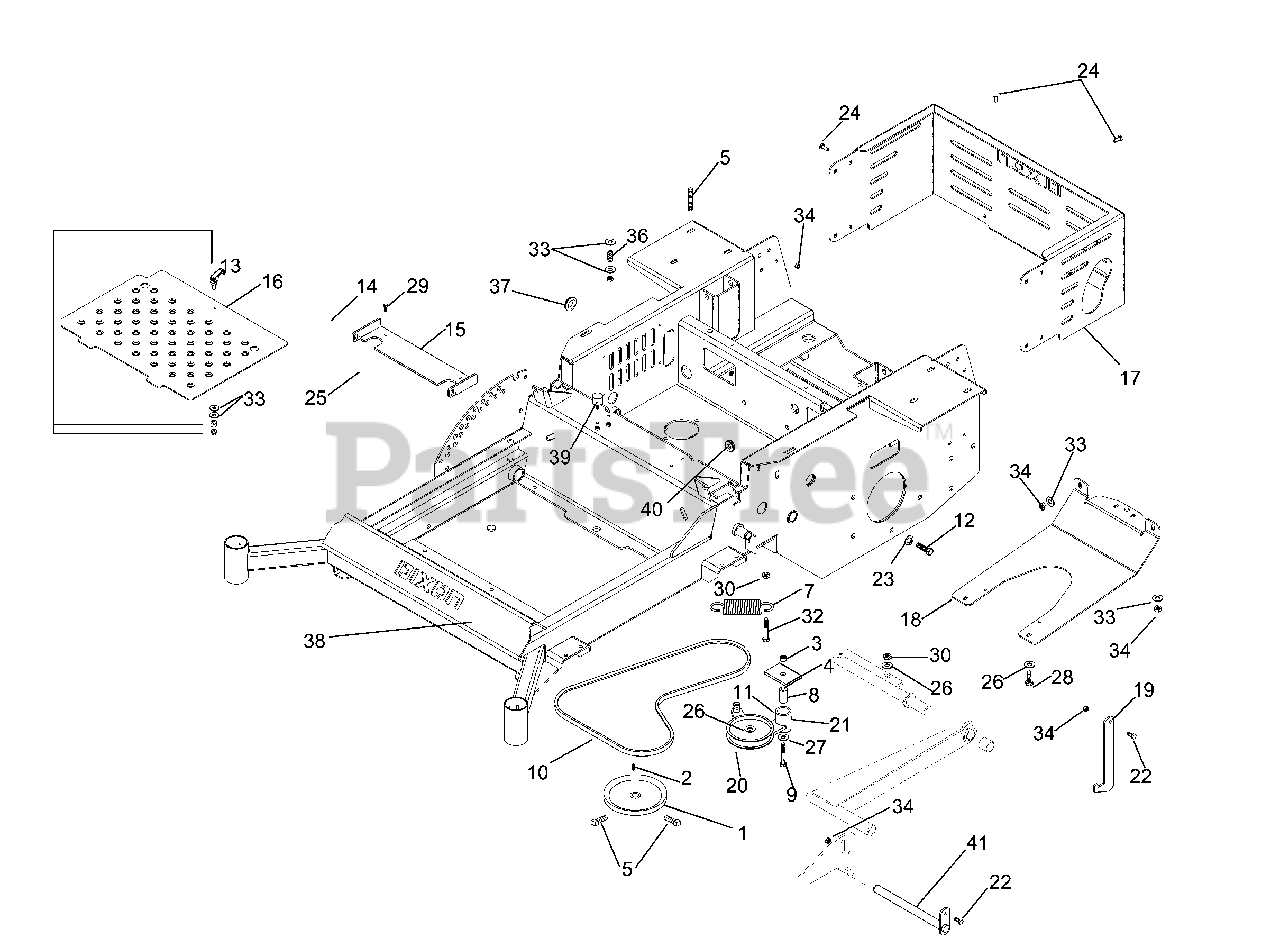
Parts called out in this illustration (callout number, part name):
2	KEY 5 MM SQ X 25 MM
3	NUT 1/2-13 HEX NYLOC ZD
5	STUD, 5/16C
6	SCREW 5/16C X 5/8 SQ HEAD
8	PIVOT BUSHING
9	HCS 1/2C X 3 1/4
10	PUMP BELT
11	IDLER ARM WLDT
12	HEX SCREW 7/16-14 X 1 GR8
13	LATCH.SWELL.ACTION
14	CLEVIS PIN 3/8
15	PLATE, MOUNT, SEAT
16	FLOOR PLT W/DECAL
17	GRD, REAR W/DECAL
18	PLATE, SKID
19	STOP, SEAT
20	IDLER PULLEY
21	ZERK
22	HCS 5/16C X 1
23	WASHER 7/16 LOCK
24	BOLT 5/16C X 3/4" CARRIAGE
25	COTTER PIN 1/8 X 3/4
26	BUSHING, IDLER FLANGE
27	WASHER 1/2 FLAT
28	HCS 3/8C X 1
29	HCS 1/4C X 3/4 HCS
30	NUT 3/8C WHIZ
31	COTTER PIN
32	HCS 3/8C X 1 1/2
33	WASHER 5/16 FLAT
34	NUT 5/16 NYLOC
37	GROMMET
38	FRAME W/DECALS
39	STUD/PLATE MOUNT
40	GROMMET, FUEL LINE
41	PIVOT PIN
